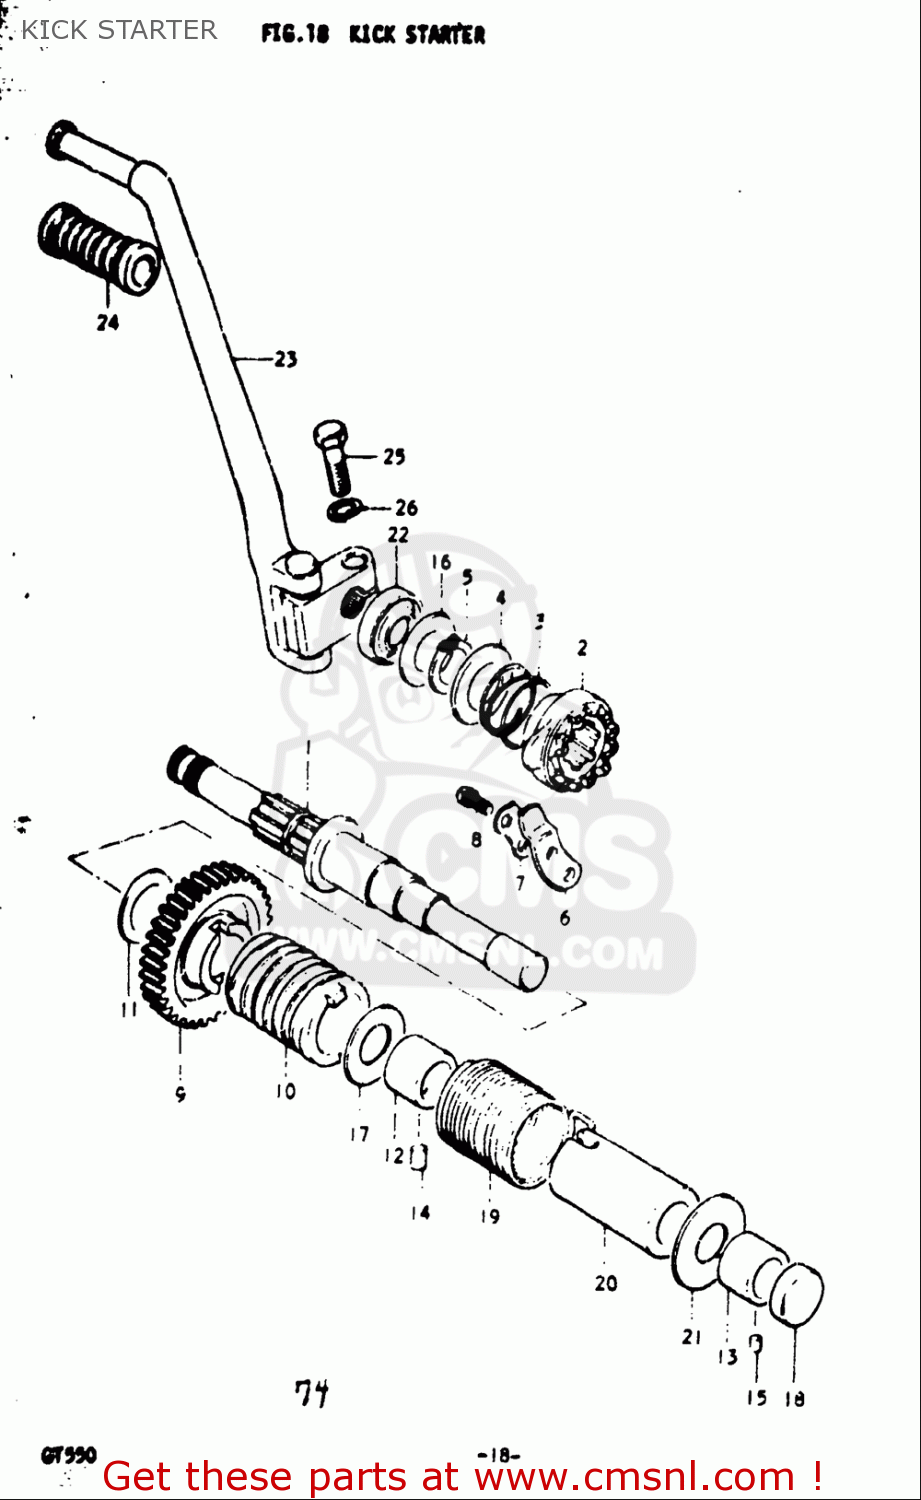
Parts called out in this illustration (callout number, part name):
2	STARTER,KICK
3	SPRING
5	CIRCLIP
8	BOLT
11	SHIM(20X28X1)
14	PIN
15	PIN
16	THRUST WASHER
17	WASHER
18	PLUG
19	SPRING
22	SEAL,OIL(16X30X8)
24	RUBBER,KICK STARTER PEDAL
25	BOLT
26	WASHER,LOCK
